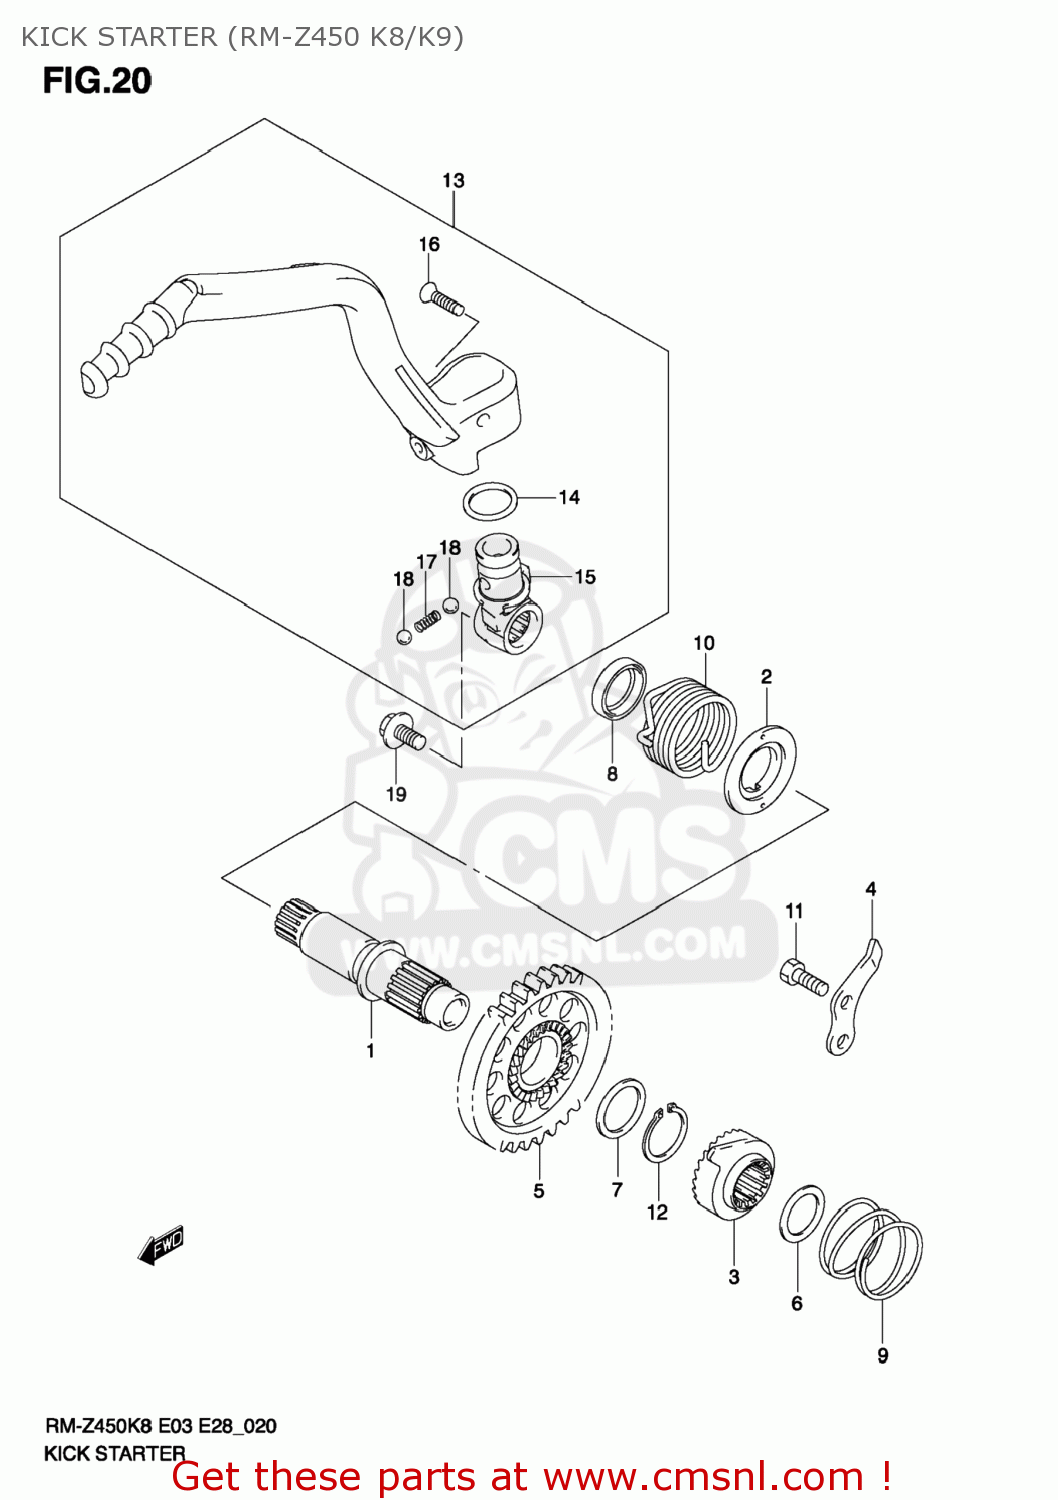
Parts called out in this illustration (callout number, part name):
1	SHAFT,KICK STARTER
2	GUIDE,KICK STARTER SFT SPRING
3	STARTER,KICK
4	GUIDE,KICK STARTER
5	GEAR,KICK STARTER DRIIVE
6	SHIM(17X24X0.5)
7	SHIM(20X26X1)
8	SEAL,OIL(20X27X5)
9	SPRING
10	SPRING
11	BOLT
12	CIRCLIP
13	LEVER ASSY,KICK STARTER
14	O RING,KICK STARTER
15	JOINT,KICK STARTER LEVER
16	SCREW(6X27.5)
17	SPRING
18	BALL
19	BOLT(8X14)
